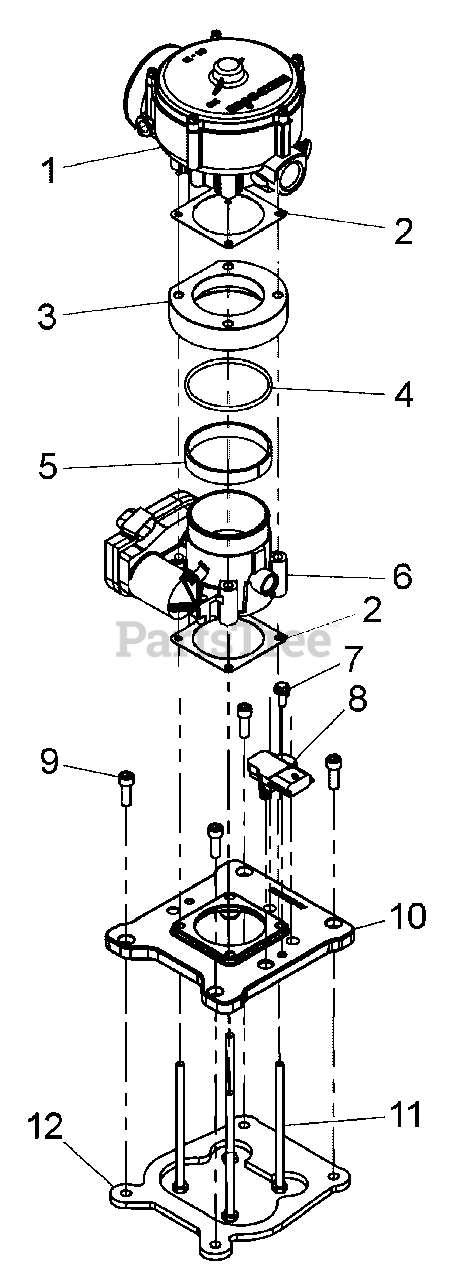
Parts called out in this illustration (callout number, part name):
2	GASKET
3	ADAPTER
4	O-RING
5	SLEEVE
6	THROTTLE BODY
7	SCREW
9	BOLT
11	BOLT
